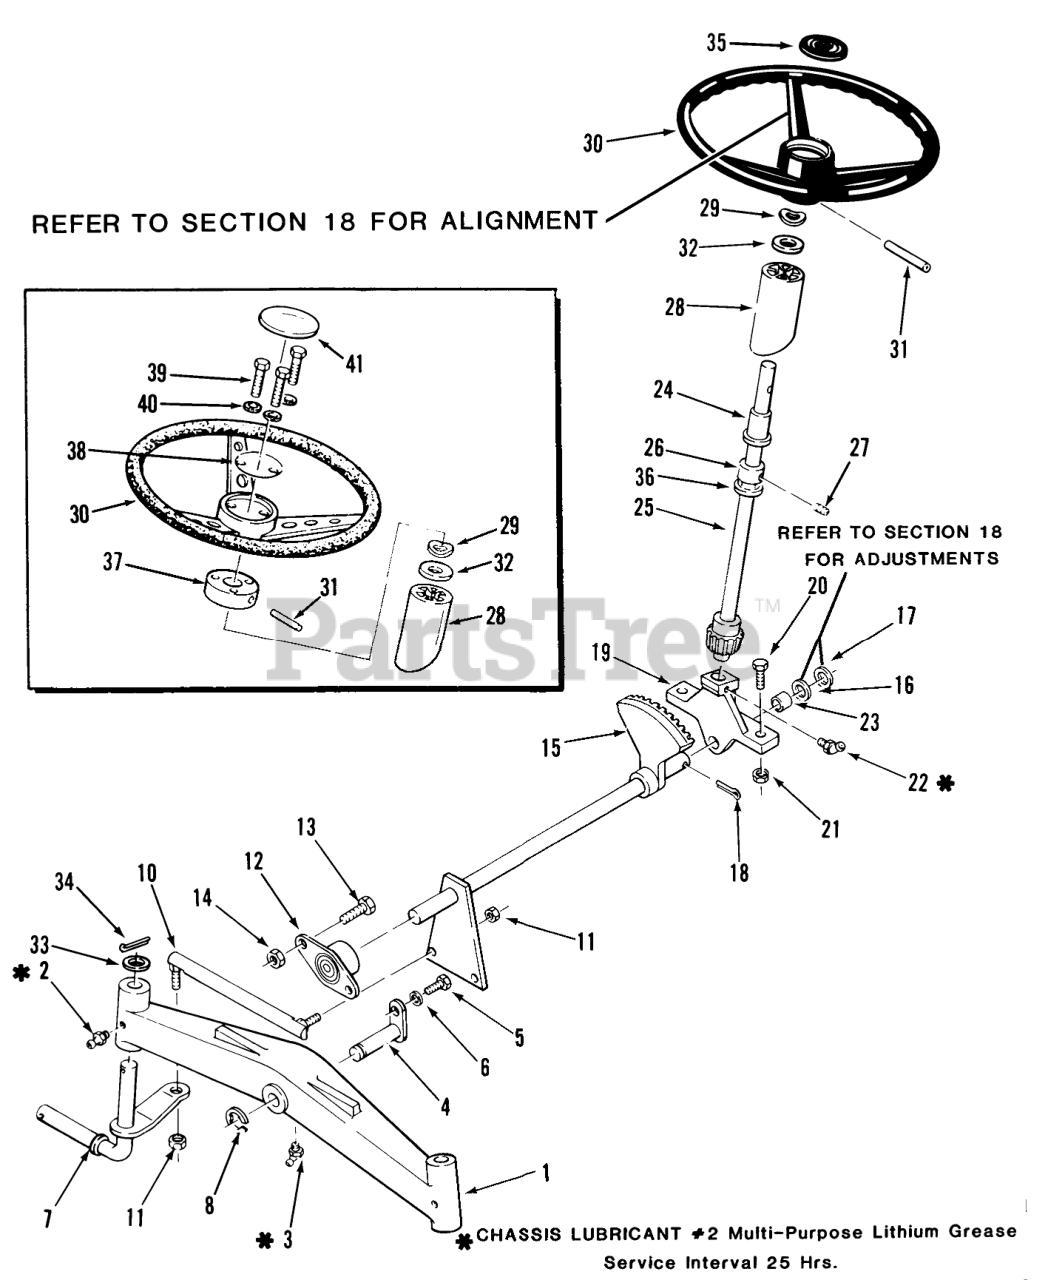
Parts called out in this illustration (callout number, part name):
1	AXLE-FRONT
2	Zerk
3	FITTING-GREASE
4	PIN AND PLATE ASM
5	H H C S
6	Lockwasher
7	Front Spindle RH 300 Series Only
7	Front Spindle LH 300 Series Only
8	E-RING
10	Tie Rod RH
11	NUT-6
12	BEARING-FLANGED
13	Bolt
14	Nut
15	Lower Steering Shaft
16	WASHER-SHIM
17	WASHER
18	PIN-4
19	Support
20	BOLT
21	Nut
22	FITTING-GREASE
23	BEARING-BRONZE
24	BEARING-FLANGED
25	Shaft-Upper Steering
26	Collar
27	SCREW-SET
28	Collar
29	WASHER-BOWED
30	STEERING WH 13" SOFT
30	STEERING WH 13" PLAS
31	Pin-Roll
32	WASHER-FLAT
33	WASHER
34	COTTER PIN-4
35	STEERING WHEEL INSE
36	RING-RETAINING
37	ADAPTER STEERING WHE
38	RETAINER CAP
39	Hex Bolt 1/4-20 x 3/4 420-LSE Only
40	Washer
